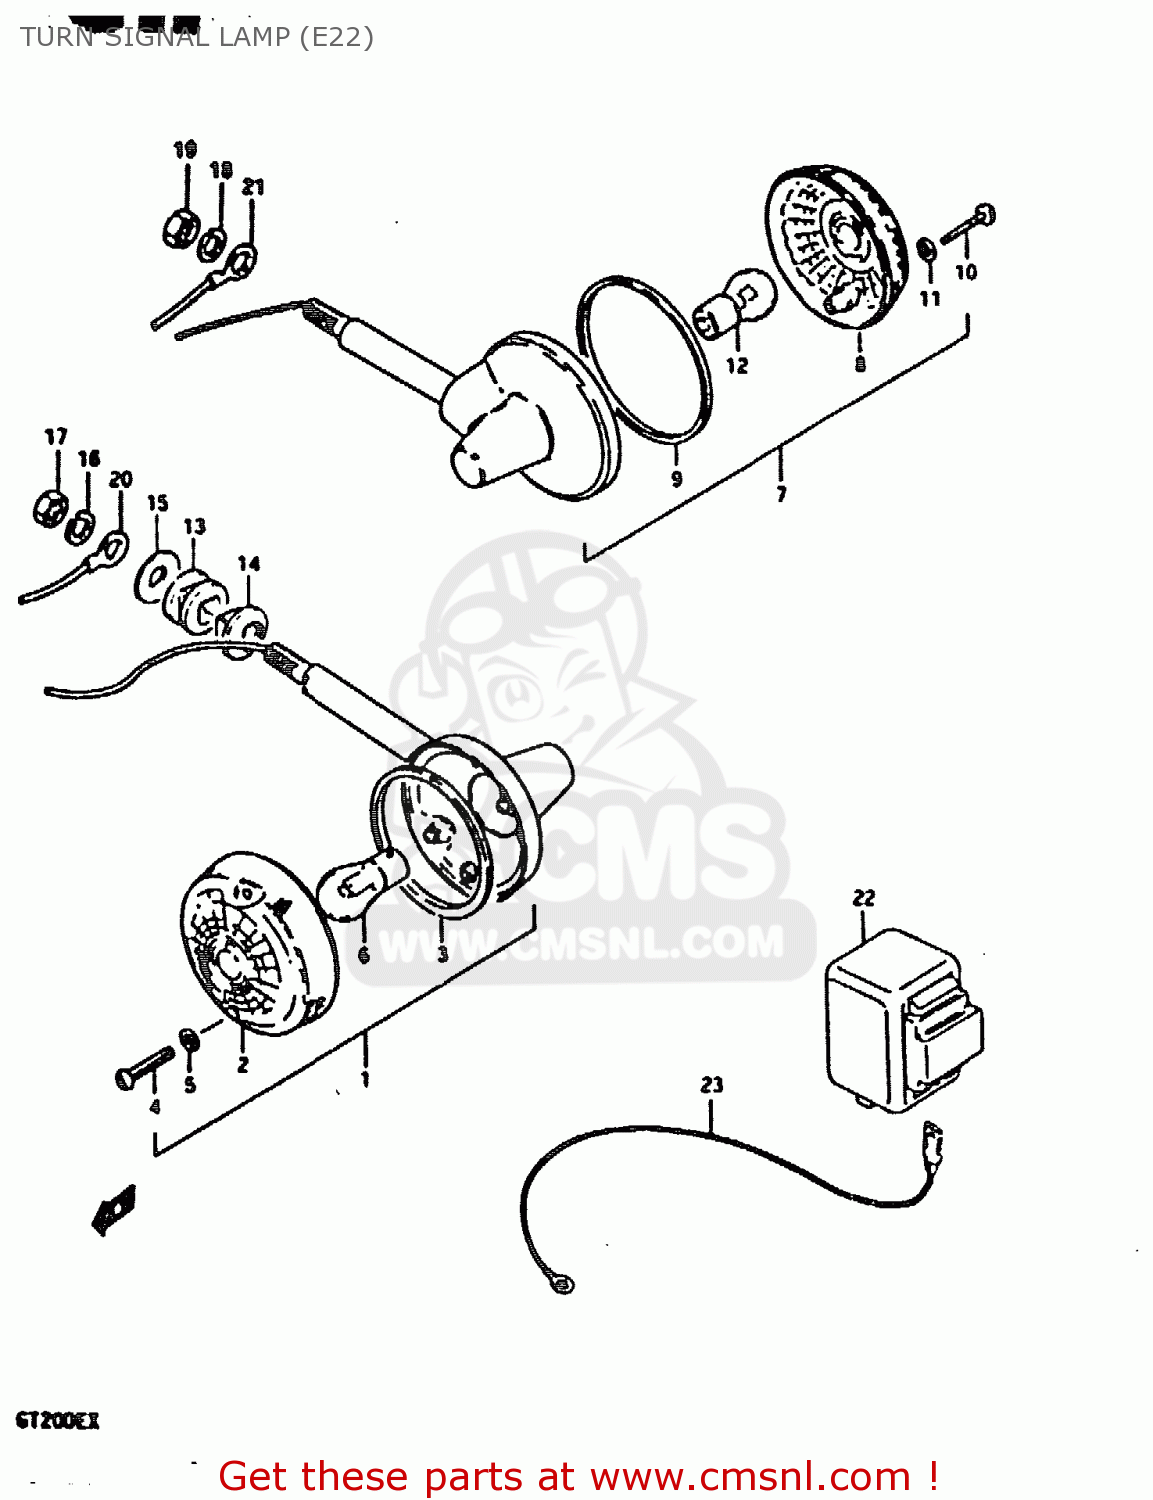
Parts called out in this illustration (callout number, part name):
1	LAMP, FRONT TURN SIGNAL
2	LENS
3	GASKET (NAS)
4	SCREW 4X25
5	GASKET (NAS)
6	BULB(12V21W)
7	LAMP, REAR TURN SIGNAL
8	LENS
9	GASKET (NAS)
10	SCREW 4X25
11	GASKET (NAS)
12	BULB(12V21W)
13	CUSHION
14	SPACER
15	WASHER (10.5X30X2.3)
16	LOCK WASHER
17	NUT
18	LOCK WASHER
19	NUT
20	LEAD WIRE,EARTH
21	LEAD WIRE, EARTH
22	RELAY, TURN SIGNAL
23	LEAD WIRE, RELAY EARTH
